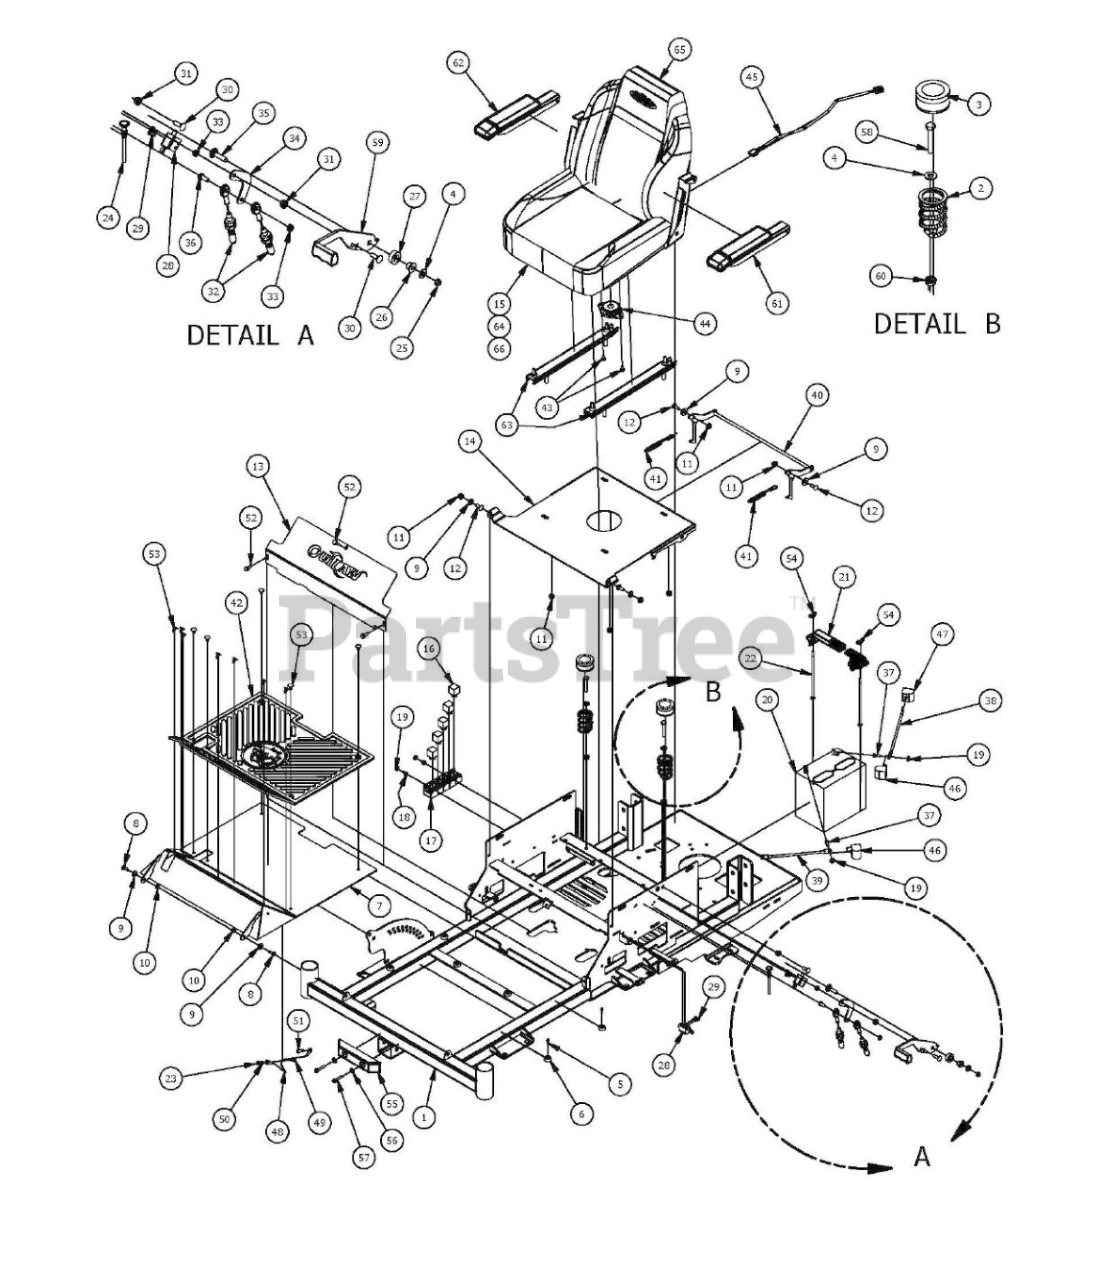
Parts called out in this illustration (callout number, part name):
1	2017 Compact Outlaw Frame
2	Seat Spring
3	Seat Spring Cap Cover
4	3/8" Flat Washer
5	#10 x 1/2" Self Taping Screw
6	Button Bumper
7	Compact Outlaw Floorboard
8	1/4" x 3/4" Carriage Bolt
9	.360 ID Plastic Washer
10	1/4 Nylock Nut
11	5/16-18 Nylon Flange Nut
12	5/16" x 7/8" Carriage Bolt
13	Compact Outlaw Cooler Cover
14	Seat Plate 2016
15	Compact Outlaw Seat
17	Wire Harness
18	1/4" x 1/2" BS C/S 18-8 SS
19	1/4-20 Hex Flange Nuts Zinc w/Serrations
21	Battery Hold Down
22	1/4-20 X 8 Carriage Bolt
23	1/4-20 Hex Nut
25	3/8-16 Centerlock Half Nut
26	Bronze Bushing SF-1220-8
27	2015 Brake Lever Spacer
28	Safety Switch
29	12-24x 1/2 HWH Bolt
30	5/16" x 1" Carriage Bolt
31	5/16" Flange Nut w/Serrations
32	Brake Cable
33	5/16-18 Nylock Jam Nut 1/2 Nut
34	Brake Cable Adapter Bracket
35	3/8 x 1 1/2 Carriage Bolt
36	5/16" x 3/4" Hex Bolt
37	1/4" x 3/4" Hex Bolt
38	24" Red Battery Cable
39	Ground Cable
40	Seat Latch Rod Assembly
41	Seat Latch Spring
42	Compact Outlaw Floor Mat
43	1/4-20x1/2 HWH Bolt Slot
44	Seat Safety Switch
45	Seat Switch Adapter
46	Black Boot For Ground Cable
48	Floor board Cable W/ Swivel Ends
49	1/4" x 5/8" BS C/S 18-8 SS
50	1/4" Lock Washer
51	1/4 x 1 Hex Head Tek screw
52	5/16 x 3/4 washer head type F screw
53	5/8" Christmas Tree Fastener
54	1/4" Wing Nut
55	8" Rubber Bumper
56	5/16" Flat Washer
57	1/4" x 1 1/2" Self Tapping Screw
58	3/8"-16 x 2" Gr 5 Hex Bolt
59	Brake Handle
60	3/8" Flange Nut
61	Left Arm Rest
62	Right Arm Rest
63	Seat Rails
65	Seat Back Cover
66	Seat Bottom Cover
